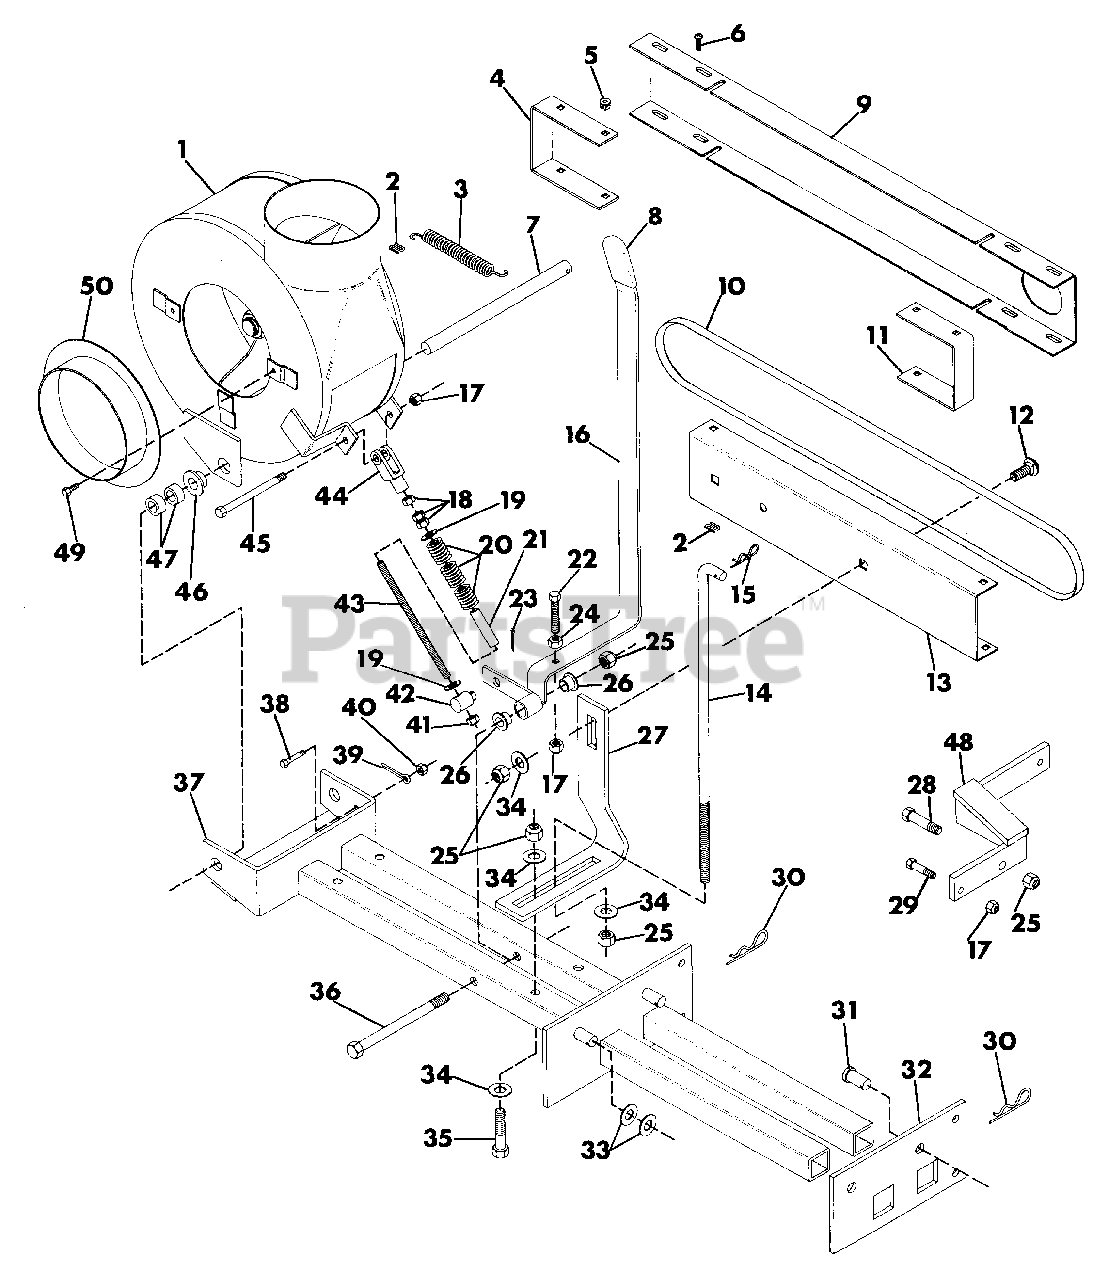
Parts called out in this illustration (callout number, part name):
1	BLOWER
2	CLIP, SPRING
3	SPRING, EXT 5.5X.5X20 RATE
4	GUIDE, RIGHT HAND
5	GROMMET, PLASTIC
6	SCREW, MACHINE 1/4-20X.5
7	ROD, BLOWER PIVOT
8	GRIP, HANDLE
9	COVER, BELT
10	BELT
11	GUIDE, LEFT HAND
12	BOLT, CARRIAGE 1/2-13X1.25
13	CHANNEL, GUARD
14	ROD
15	PIN, COTTER HAIR
16	WELDMENT, HANDLE
17	NUT, LOCK 3/8-16
18	NUT, HEX 3/8-24
19	WASHER, FLAT .406X.812X.065
20	SPRING, COMP. 1X.78X388 LB/IN
21	SLEEVE, SPRING
22	BOLT, 3/8-16X2 ALL THREAD
23	PIN, COTTER 1/8X1
24	NUT, JAM 3/8-16
25	NUT, LOCK 1/2-13
26	BUSHING
27	BRACKET
28	BOLT, HEX 1/2-13X2
29	BOLT, HEX 3/8-16X1.5
30	PIN, HAIR
31	PIN, CLEVIS 5/8X1.125
32	PLATE
33	WASHER, FLAT .656X1.312X.095
34	WASHER, FLAT 1.38X.56
35	BOLT, HEX 1/2-13X2.75
36	BOLT, HEX 1/2-13X5.5
37	WELDMENT, BLOWER FRAME
38	BOLT, HEX 1/4-20X.75
39	PIN, COTTER .25X2
40	NUT, LOCK 1/4-20
41	NUT, LOCK 3/8-24
42	TRUNNION
43	ROD, ACTUATOR
44	CLEVIS, 3/8-24 ADJUSTABLE
45	BOLT, HEX 3/8-16X4.5
46	BUSHING, NYLON .76X1X.6 FLG.
47	SPACER .760X1X.540
48	WELDMENT, SUPPORT
49	BOLT, HEX 5/16-18X.75
50	ADAPTOR, HOSE
NS	DECAL, GRAVELY LOGO
NS	DECAL, PTO
